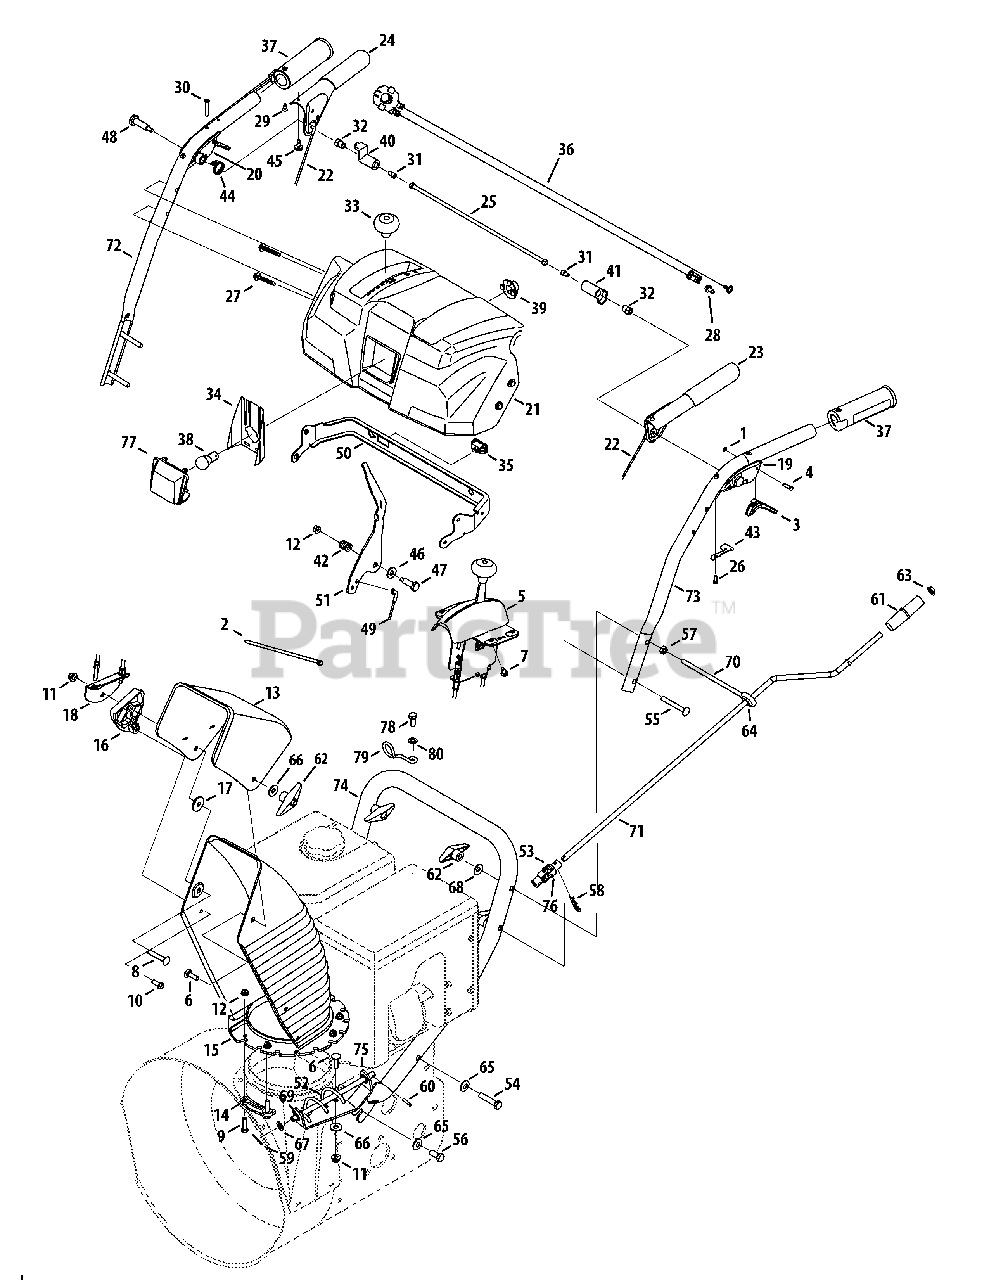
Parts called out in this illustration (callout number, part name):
2	Cable Tie
3	Trigger Lock
5	Chute Control Assembly
6	Carriage Screw, 5/16-18 x 1.0
7	Screw, 1/4-15 x .50
8	Carriage Screw, 5/16-18 x 1.75
9	Hex Screw 1/4-20 x 1.0
10	Screw, 1/4-15 x .750
11	Flange Lock Nut 5/16-18
12	Flange Lock Nut 1/4-20
13	Upper Chute, 6.0
14	Chute Flange Keeper
15	Lower Chute
16	Cbl. Guide, Chute Tilt
17	Flat Wash, .344 x 1.125 x .12
18	Cable Bracket
19	Handle Assembly, LH
20	Handle Assembly, RH
21	Handle Panel
22	Cable Ass’y, Auger/Drive
23	Engagement Handle, LH
24	Engagement Handle, RH
25	Clutch Lock Rod Assembly
26	Screw, #8-16 x .50
27	Screw, 1/4-20 x 1.625
28	Hex Screw, 1/4-20 x .5
29	Screw, #10-16 x .625
30	Screw, #10-24 x 1.375
31	Screw, 1/4-20 x .50
32	Nut, Hex, 1/4-20
33	Shift Knob
34	Lens Lable
35	Heated Grip Switch
36	Wire Harness
37	Heated Grip
38	Lamp, 12.8V
39	Light Socket
41	Clutch Lock Cam
42	Compression Spring
43	Clutch Lock Spring
44	Torsion Spring, .8156 ID x .3038
45	Rubber Bumper
46	Flat Washer, .385 x .87 x .06
47	Screw, Shldr., .374 x 1.05
48	Screw, Shldr., .437 x 1.345
49	Clutch Cable
50	Panel Bracket
52	Chute Crank Assembly
53	Joint Block Assembly
54	Hex Screw, 3/8-16 x 2.00
55	Carriage Screw, 5/16-18 x 2.5
56	Screw, Hex, 3/8-16 x 1.00
57	Nut, Hex, 5/16-18
58	Internal Cotter Pin
59	Pin, Bow-tie Cotter
60	Spring Pin, .156 dia. x .875 Lg.
61	Knob, Crank
62	Knob, Wing Nut, 5/16-18
63	Push Cap, 3/8
64	Rubber Grommet
65	Bell Wash, .375 x .87 x .063
66	Flat Washer, .349 x .879 x .063
67	Flat Wash, .375 x .738 x .063
68	Wash, Bell, .34 x .872 x .06
69	Plastic Bushing, .38 ID
70	Eye Bolt, .70 Dia.
71	Chute Rod, .375 Dia. x 29.72
72	Handle, Upper, RH
73	Handle, Upper, LH
74	Handle, Lower
75	Chute Crank Bracket
76	Roll Pin, 3/16 Dia. x 1.100
78	Hex Screw, M8-1.25
79	Cable Guide
80	Flat Washer, .330 x .630 x .0635
